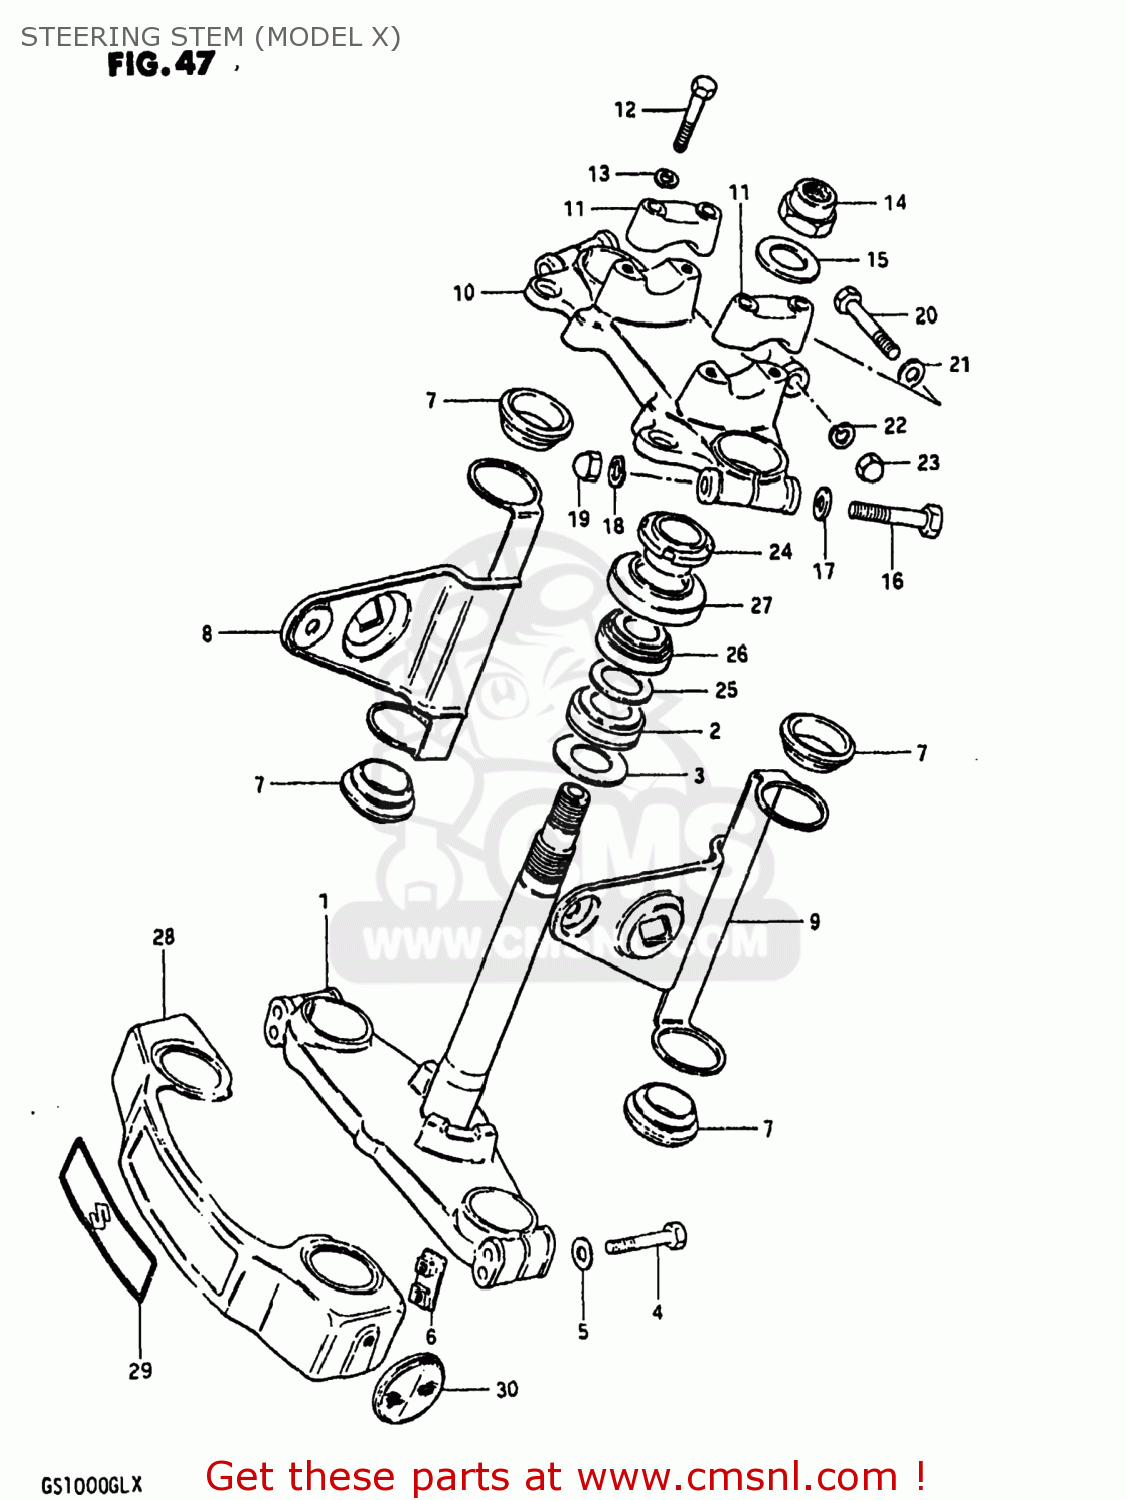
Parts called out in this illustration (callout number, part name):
1	STEM,STEERING
2	BEARING
3	WASHER,THRUST
4	BOLT 8X55
5	WASHER
6	NUT,FR FORK INNER TUBE
7	CUSHION,HEADLAMP BRACKET
8	BRACKET,HEADLAMP,RIGHT
9	BRACKET,HEADLAMP,LEFT
10	HEAD,STEERING STEM
11	HOLDER,HANDLE(BLACK)
12	BOLT
13	LOCK WASHER
14	NUT,FR FORK UPR BRACKET
15	WASHER
16	BOLT 10X55
17	WASHER
18	LOCK WASHER
19	NUT, LOWER LH
20	BOLT 8X50
21	WASHER
22	WASHER,LOCK,8.
23	NUT
24	NUT,STEERING STEM
25	WASHER(18.5X24X1)
26	TAPER,ROLLER BEARING
27	DUST SEAL,STEERING,UPPER
28	COVER,FRONT FORK
29	EMBLEM,FR FORK COVER
30	REFLEX REFLECTOR,RR
